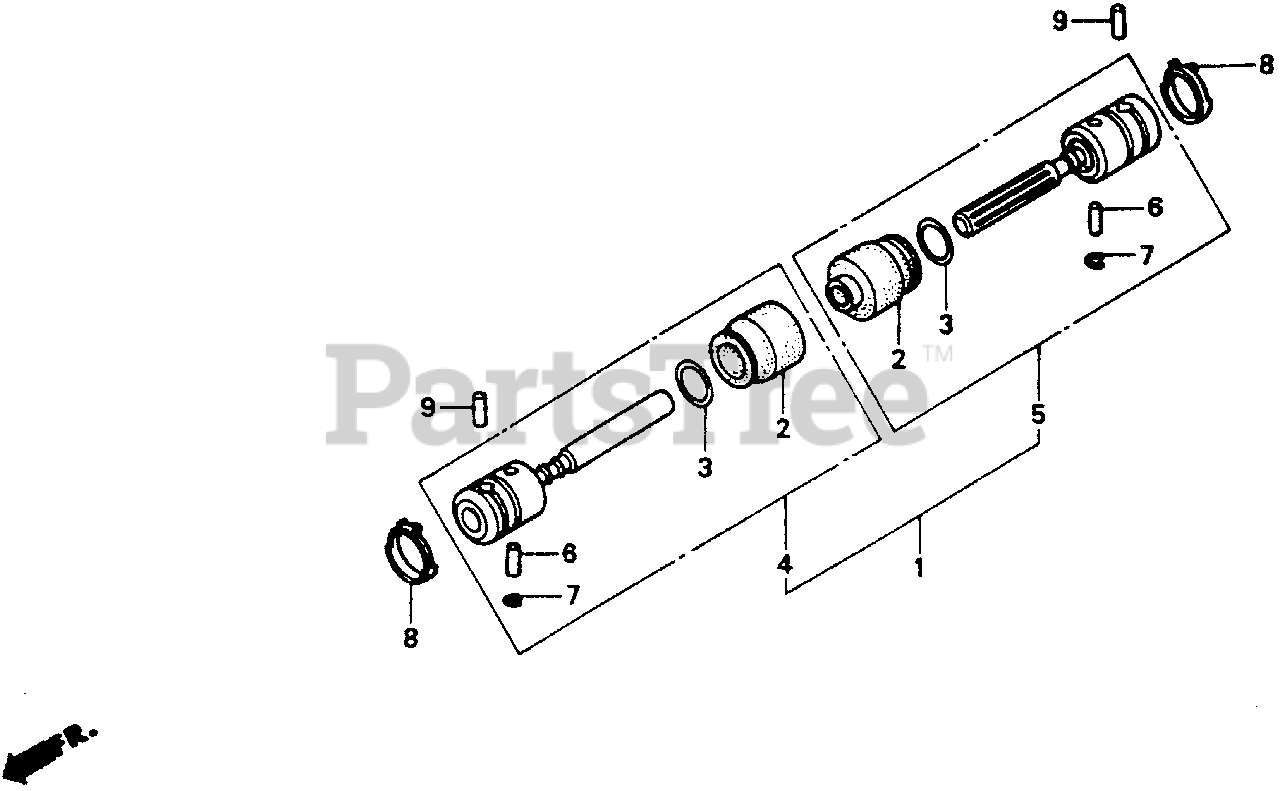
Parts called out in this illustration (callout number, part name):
1	JOINT ASSY.
2	BOOT, JOINT
3	RING, SEAL
4	JOINT SUB-ASSY. (A)
5	JOINT SUB-ASSY. (B)
5	JOINT SUB-ASSY. (B) (NA USE ALT:22100-VB5-L01)
6	PIN, DRIVE
7	RING, SNAP
8	CLIP, CLUTCH SHAFT
9	ROLLER (4X17.8)
